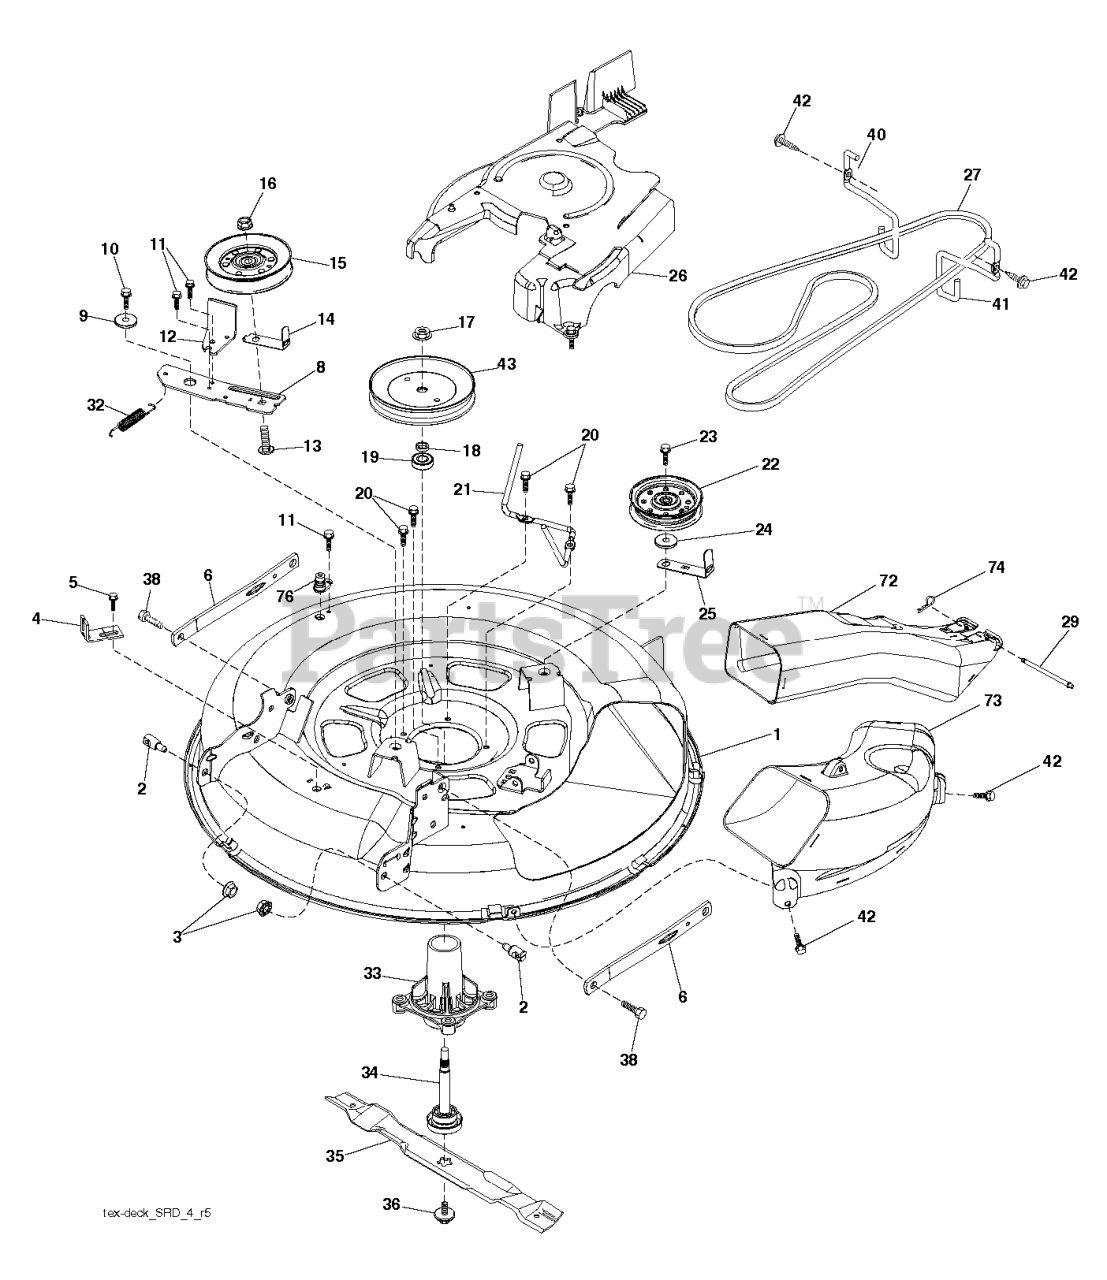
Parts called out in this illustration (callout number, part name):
1	DECK.WELDMENT.30"SRD.BLACK
2	STUD.FASTNER.W/ANTI-ROTATE
3	NUT LOCK HEX FLANGE 5/16-18
4	BRACKET.CLUTCH.CABLE
5	BOLT.5/16HEX.WHS.HD
6	ARMS.SUSP.MOWER.REAR.SRD
8	ARM.IDLER.30"SRD
9	SPACER.RETAINER
10	SCREW 3/8-16X1
11	SCREW.1/4-20X5/8
12	RP ARM.BRAKE.MOWER.38"LH.TEX
13	BOLT.3/8-16X1.50
14	KEEPER, BELT IDLER
15	PULLEY.IDLER.4.25
16	NUT LOCK FLG 3/8-16 UNC
17	NUT.FLANGE.LOCK.TOP
18	WASHER.SPACER.MANDREL
20	SCREW, WASHER HEAD
21	KEEPER.BELT.MANDREL.30"
22	PULLEY.IDLER.FLAT.UNPLATED
23	SCREW LT
24	WASHER
25	KEEPER.BELT.30"SRD
27	V-BELT.DRIVE.MOWER.30"
29	PIN.HINGE.30".SRD
32	SPRING.MOWER.DRIVE.ELECTRIC
33	RP.HOUSING.MANDREL.4PT.
34	SHAFT.ASM.MDRL.N/GREASE.38
35	BLADE.MOWER.BAGGING.30"
36	BOLT.WASHER.ASM.7/16-2
38	BOLT.SHOULDER
40	KEEPER.BELT.ENGINE.LH.LT.SRD
41	KEEPER.BELT.ENGINE.RH.LT.SRD
42	SCREW, 3/8-16X3/4
43	PULLEY, MANDREL 6.5 PD
72	CHUTE.UPPER.SRD.30R"
73	CHUTE.LOWER.SRD.30R"
74	RETAINER-SPRNG RB
76	PORT.WASHOUT
